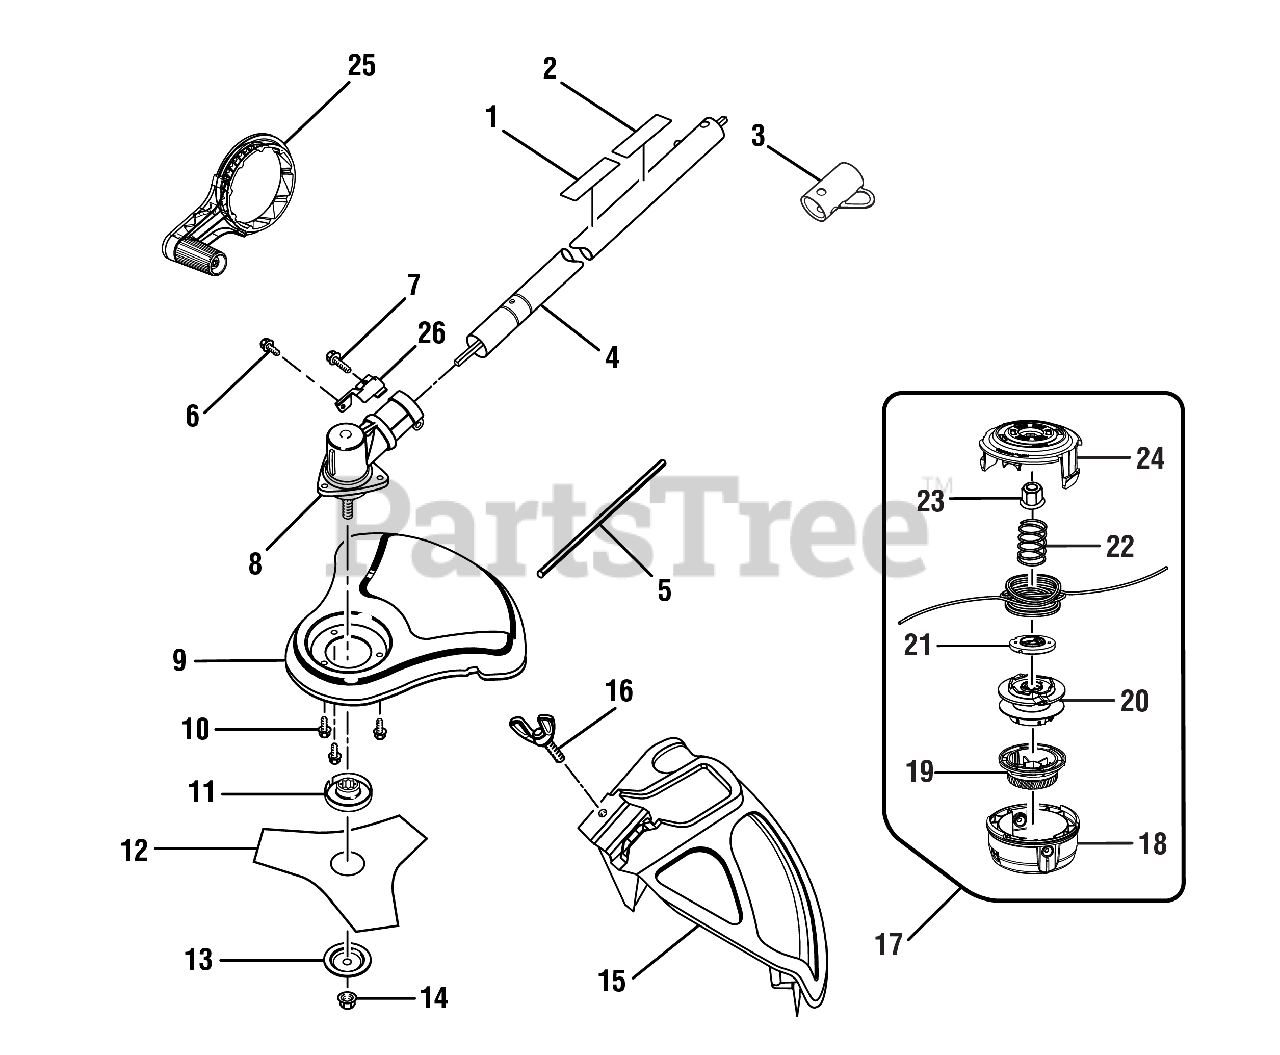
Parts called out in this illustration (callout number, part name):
1	Ryobi EXPAND-IT Label
2	Brushcutter Safety Label
3	Storage Hanger Cap
4	Lower Straight Shaft Boom Assembly
5	Gear Head Locking Tool
6	Screw (1/4-20 x 1-1/4 in., Hex Washer Hd. S.T.)
7	Screw w/Washer (10-24 x 5/8 in., Hex Hd. T.F.)
8	Gear Case Assembly
9	8 in. Blade Guard
10	Screw w/Washer (10-24 x 1/2 in., Slotted Hex Hd.)
11	FLANGED WASHER
12	BLADE (TRI-ARC(TM))
13	CUPPED WASHER
14	Lock Nut (M8 x 1.25 in., Left Hand Threads)
15	Grass Deflector Assembly (Inc. Key No. 16)
16	Screw (#1/4-20 x 1-1/4 in. Hex Washer Hd.)
17	Trimmer Head Assembly (.095)
18	Lower Housing
19	Bump Knob (Green)
20	Spool Assembly
21	String Guide
22	Compression Spring
23	Hex Nut (M8, Left Hand Threads)
24	Upper Housing
25	Crank Handle Assembly
26	Grass Deflector Clamp
